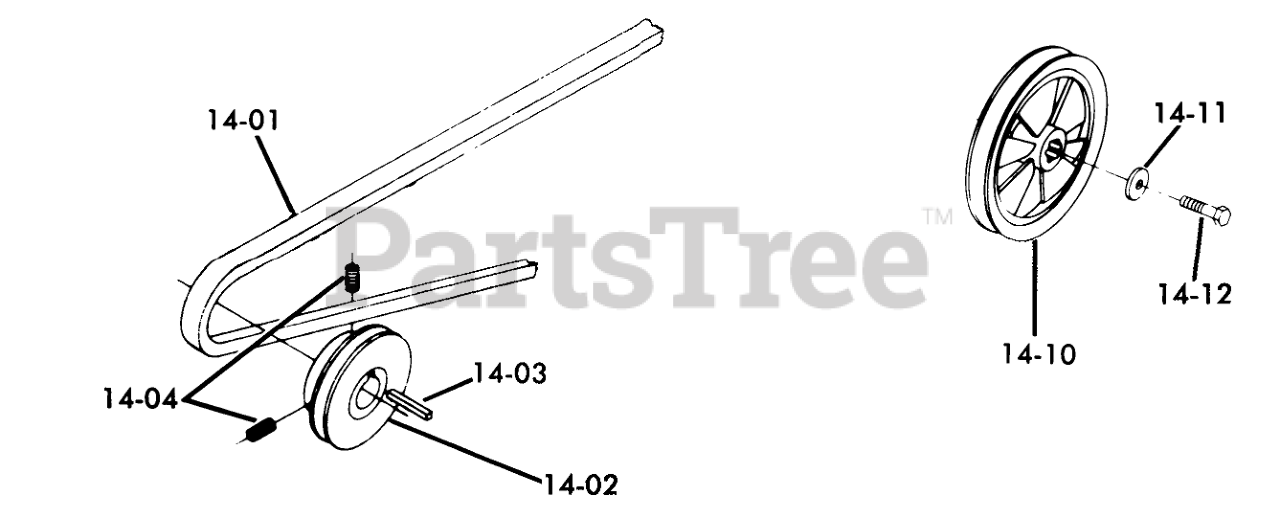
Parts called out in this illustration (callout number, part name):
14-01	V BELT
14-02	PULLEY
14-04	Set Screw
14-10	PULLEY
14-11	WASHER
14-12	Bolt
